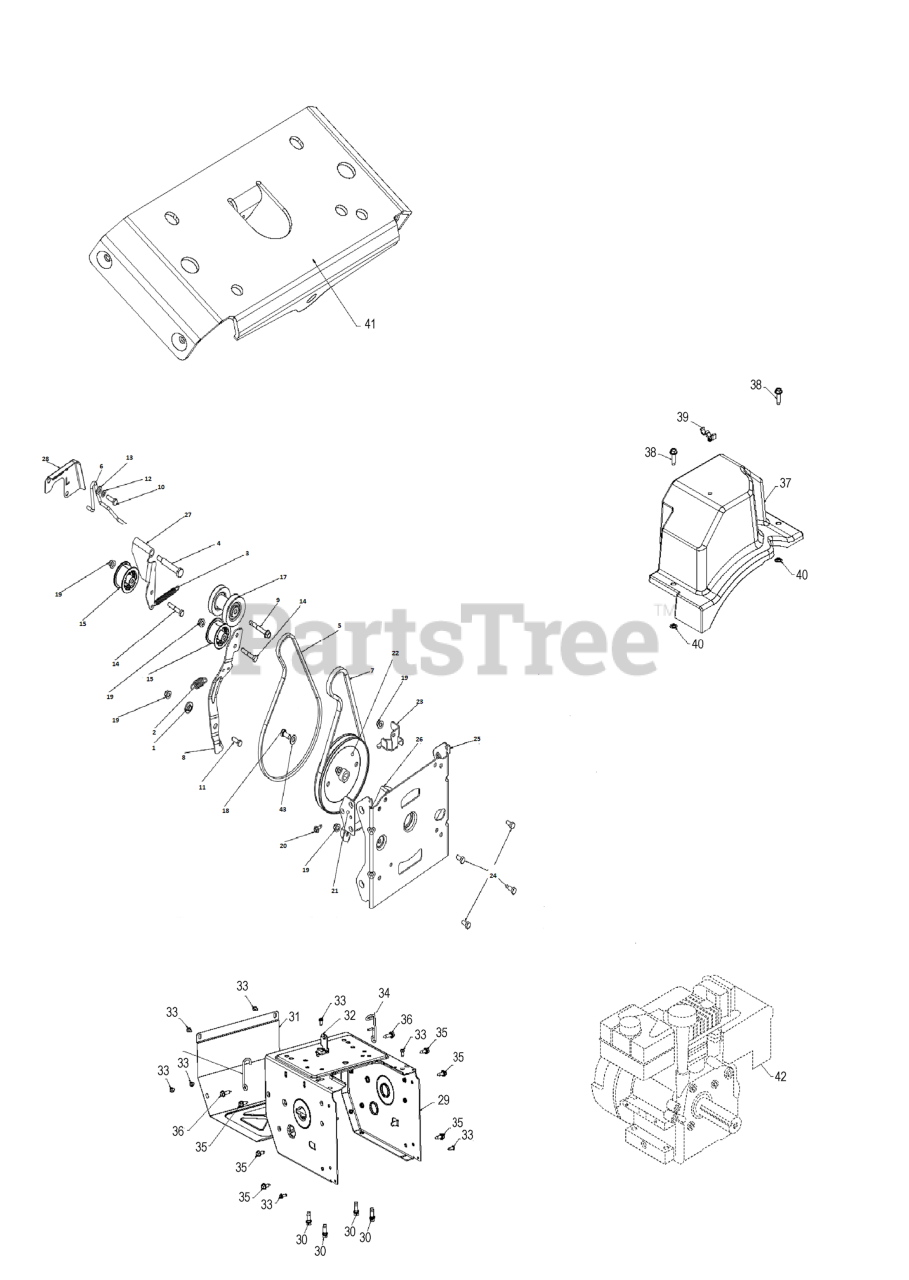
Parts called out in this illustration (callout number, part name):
1	BUSHING.BRAKE.ARM
2	SPRING RETURN, IDLER ARM, IMPE
3	SPRING RETURN IDLER ARM
4	BOLT 5/16-24X2.25 HEX HEAD SHO
6	Belt Keepers
7	LOW CRANK IMPELLER BELT
8	ARM.IDLER.AUTO-PH.676
11	BOLT HEXAGON BOLT 5/16-18 X 7/
12	WASHER SPRING LOCK WASHER WITH
13	WASHER 11/32 X 11/16 X 14 GA T
14	BOLT, HEX 5/16-18X1-3/4
15	PULLEYIDLER.2.0.W/SPACER.CZ
17	PULLEY 4L GEAR - LC
18	Bolt, Hex Head 3/8-16 x 3/4
18	SCREW HEXAGON HEAD FLANGE 3/8-
19	NUT HEXAGON FLANGE 5/16-18 ST
19	WASHER PLAIN WASHER 3/8 X 0.08
20	HEX.WASHER.HEAD 1/4-20 X .65
21	BRACKET NUT BLACK ZINC PLATE
22	PULLEY IMPELLER DD 4L
22	PULLEYS
23	GUIDE.LOWER.AUGER.BELT.479
25	BRACKET.AUG.HOUSING.INTER.BLAC
26	BRACKET.BELT.KEEPER.LOWER.BLAC
27	ARM DRIVE IDLER CLEAR ZINC PLA
29	FRAME MS 668
30	BOLT 3/8-16X1-1/8
31	COVER COVER.FRAME MS668 ORANGE
32	BRACKET.SHIFTER.BZP
33	SCREW.HEX HEAD W/COLLAR 1/4-20
34	WIREFORM.SUPPORT.CABLE
35	BOLT.HEX.HD.WASHER.5/16-18X.75
36	SCREW HEXAGON HEAD WITH COLLAR
37	COVER BELT ASM. LOW CRANK
38	SCREW HEX WASH THDRL BLK 1_4-
40	PALNUT 1/4
41	BRACKET.FRAME.SUPPORT.BLACK
42	ENGINE.LCT.254CC.ALT.SNO
42	ENGINES
42	ENGINE RATO 252CC (CARB)
43	WASHER PLAIN WASHER 3/8 X 0.08
